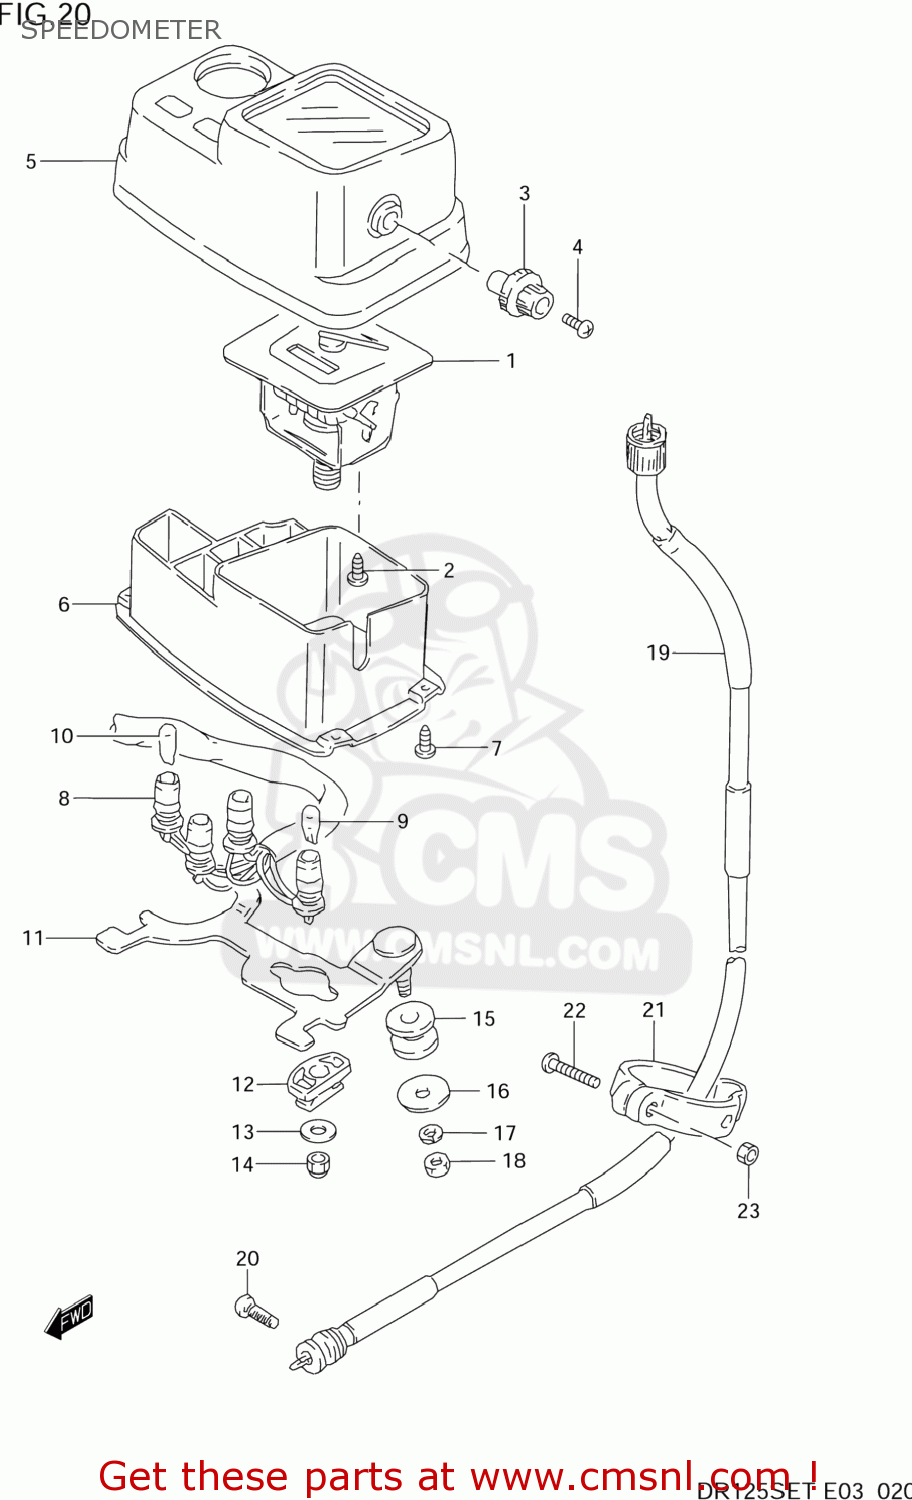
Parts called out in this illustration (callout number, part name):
1	SPEEDOMETER
2	SCREW
3	KNOB,TRIP
4	SCREW(2X6)
5	HOOD,METER
6	CASE,METER
7	SCREW
8	SOCKET ASSY
9	BULB(12V3.4W,T10)
10	BULB(12V1.7W,T10,WB121)
11	BRACKET,METER
12	CUSHION
13	WASHER (5.5X16X1.2)
14	NUT
15	CUSHION
16	WASHER
17	LOCK WASHER
18	NUT 6MM
19	CABLE ASSY,SPEEDOMETER
20	SCREW
21	CLAMP,SPEEDOMETER CABLE
22	SCREW
23	NUT
